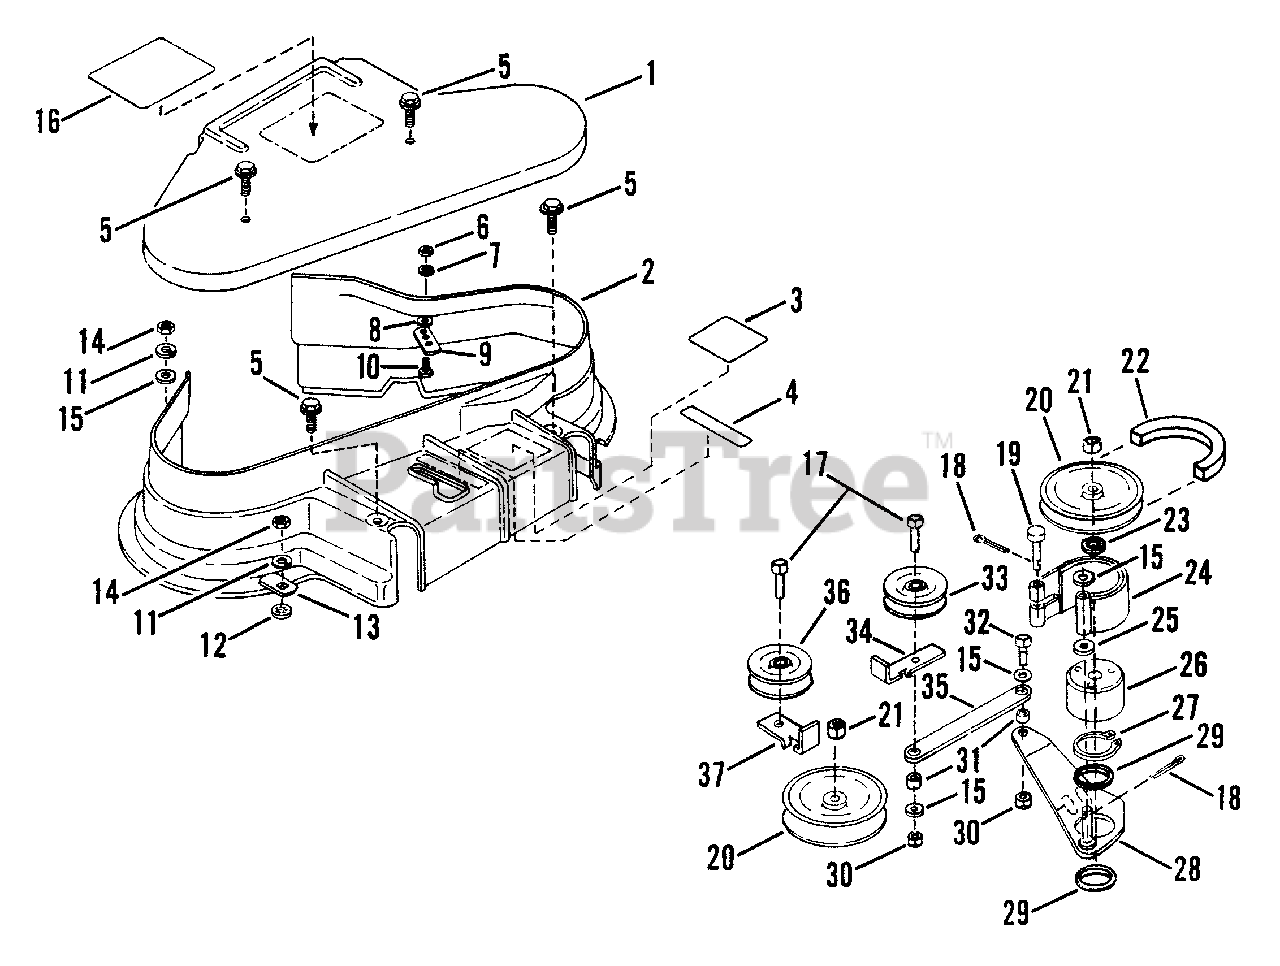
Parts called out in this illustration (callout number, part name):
1	ASSEMBLY, 42" Cover (Top)
2	ASSEMBLY, 42" Cover (Bottom)
3	DECAL, Brake Operation
4	DECAL, Blade (ON-OFF)
5	SCREW, 1/4-28 x 5/8" Self-Tapping
6	NUT, 1/4-20 Hex
7	WASHER, 1/4 Internal Tooth Lock
8	WASHER, 1/4 Flat
9	GUIDE, Belt
10	SCREW, 1/4-20 x 1/2" Hex Cap
11	WASHER, 3/8 Split Lock
12	RETAINER, 3/8 Bolt
13	CLIP
14	NUT, 3/8-16 Hex
15	WASHER, 3/8" Flat
16	DECAL, Caution
17	SCREW, 3/8-24 x 1-3/4" Hex Cap
18	PIN, 3/32 x 3/4" Cotter Hair
19	PIN, 1/4 x 1-5/8" Clevis
20	PULLEY, 5" O.D.
21	NUT, 3/4-16 Hex Jam Lock
22	BELT, AA105
23	WASHER, 3/4 Flat
24	BAND, Brake Assembly
25	SPACER
26	BRAKE DRUM
27	RING, 2" External Retaining
28	ASSEMBLY, Brake Arm
29	WASHER, 2" I.D.
30	NUT, 3/8-24 Hex Lock 12
31	SPACER
32	SCREW, 3/8-24 x 3/4" Hex Cap
33	PULLEY, Idler
34	RESTRICTOR
36	PULLEY, Idler
37	GUIDE, Belt
